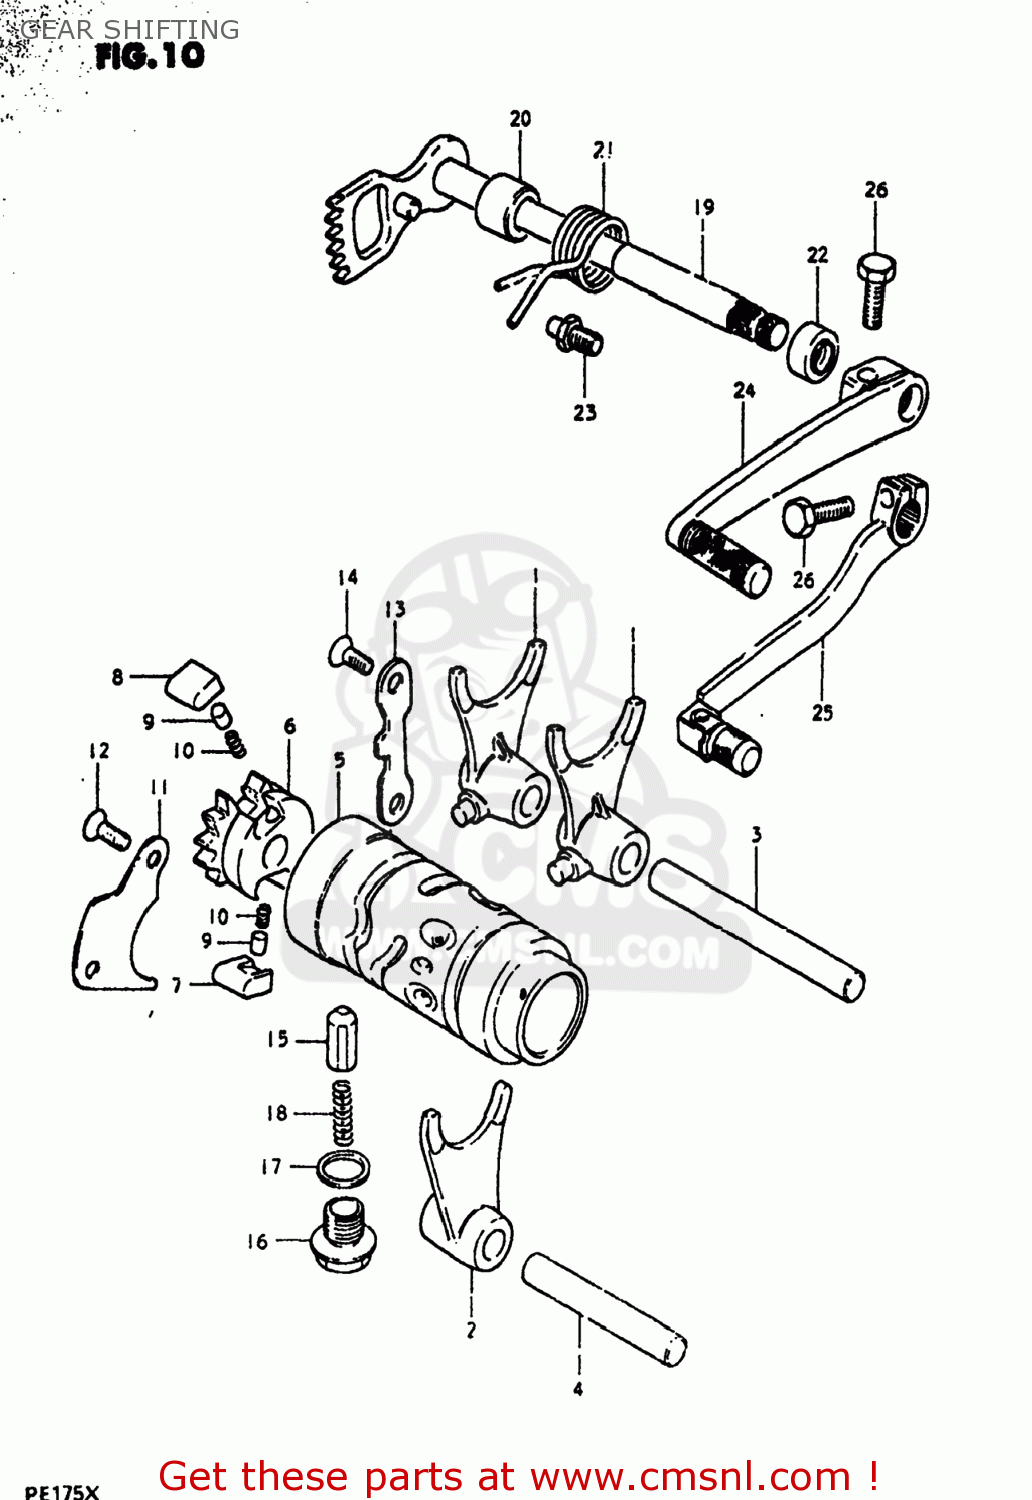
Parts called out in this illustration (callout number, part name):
1	FORK,GEAR SHIFT NO.1
2	FORK,GEAR SHIFT NO.2
3	SHAFT,GEAR SHIFT FORK
4	SHAFT,GEAR SHIFT FORK
5	CAM,GEAR SHIFT
6	RETAINER,GEAR SHIFT CAM
7	PAWL,GEAR SHIFT NO.1
8	PAWL,GEAR SHIFT NO.2
9	PIN(5X8)
10	SPRING
11	LIFTER,GEAR SHIFT PAWL
12	SCREW
13	GUIDE,GEAR SHIFT CAM
14	SCREW
15	STOPPER,GEAR SHIFTING
16	BOLT,GEAR SHAFT CAM STOPPER
17	GASKET(14X19.2X2) (NAS)
18	SPRING
19	SHAFT,GEAR SHIFT
20	SPACER(12X20X15.3)
21	SPRING
22	OIL SEAL
23	STOPPER,GEAR SHIFT CAM
24	LEVER ASSEMBLY,GEAR SHIFTING
25	LEVER ASSEMBLY,GEAR SHIFTING
26	BOLT
